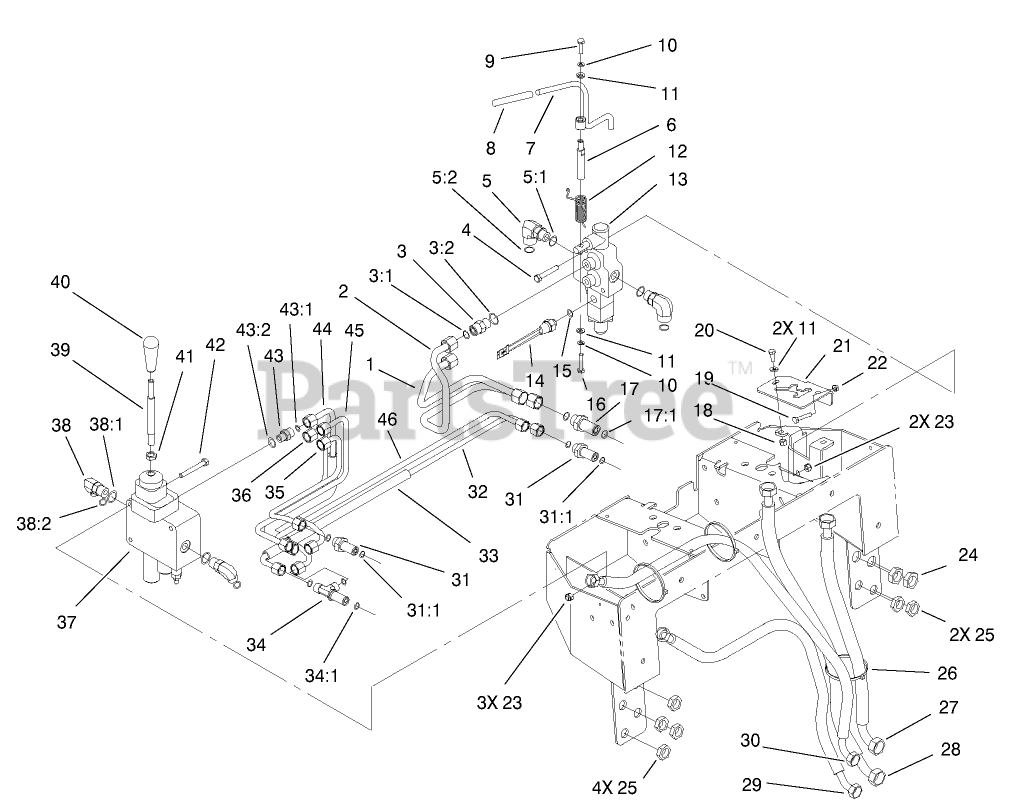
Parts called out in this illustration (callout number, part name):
1	HYD TUBE ASM
2	HYD TUBE ASM
3	FITTING-STRAIGHT
3:1	O-RING
3:2	O-RING
4	SCREW-HH
5	Fitting-Elbow, 90 DEG
5:1	O-RING
5:2	O-RING
6	Spacer-Hiflo
7	AUXILIARY LEVER ASM
8	CAP-ROD, TILT
9	SCREW-HH
10	WASHER-LOCK
11	WASHER-FLAT
12	SPRING-TORSION
13	VALVE-1 SPOOL
14	SWITCH-BALL
15	O-RING
16	SCREW-HH
17	FITTING-BULKHEAD
17:1	O-RING
18	NUT-HEX
19	SCREW-HH
20	SCREW-HH
21	AUXILIARY STOP ASM
22	NUT-JAM
23	NUT-LOCK, NI
24	NUT-BULKHEAD
25	NUT-LOCK
26	TIE-CABLE
27	HYDRAULIC HOSE ASM
28	HYD HOSE ASM
29	HYD HOSE ASM
30	HYD HOSE ASM
31	FITTING-STRAIGHT, BULKHEAD
31:1	O-RING
32	HYD TUBE ASM
33	CONDUIT-CONVOLUTED
34	FITTING-TEE, BULKHEAD
34:1	O-RING
35	HYD TUBE ASM
36	HYD TUBE ASM
37	VALVE-2 SPOOL
38	FITTING-ELBOW-90 DEG
38:1	O-RING
38:2	O-RING
39	SHAFT-HANDLE, LIFT/TILT
40	KNOB-TAPERED
42	SCREW-HH
43	FITTING-STRAIGHT
43:1	O-RING
43:2	O-RING
44	HYD TUBE ASM
45	HYD TUBE ASM
46	HYD TUBE ASM
